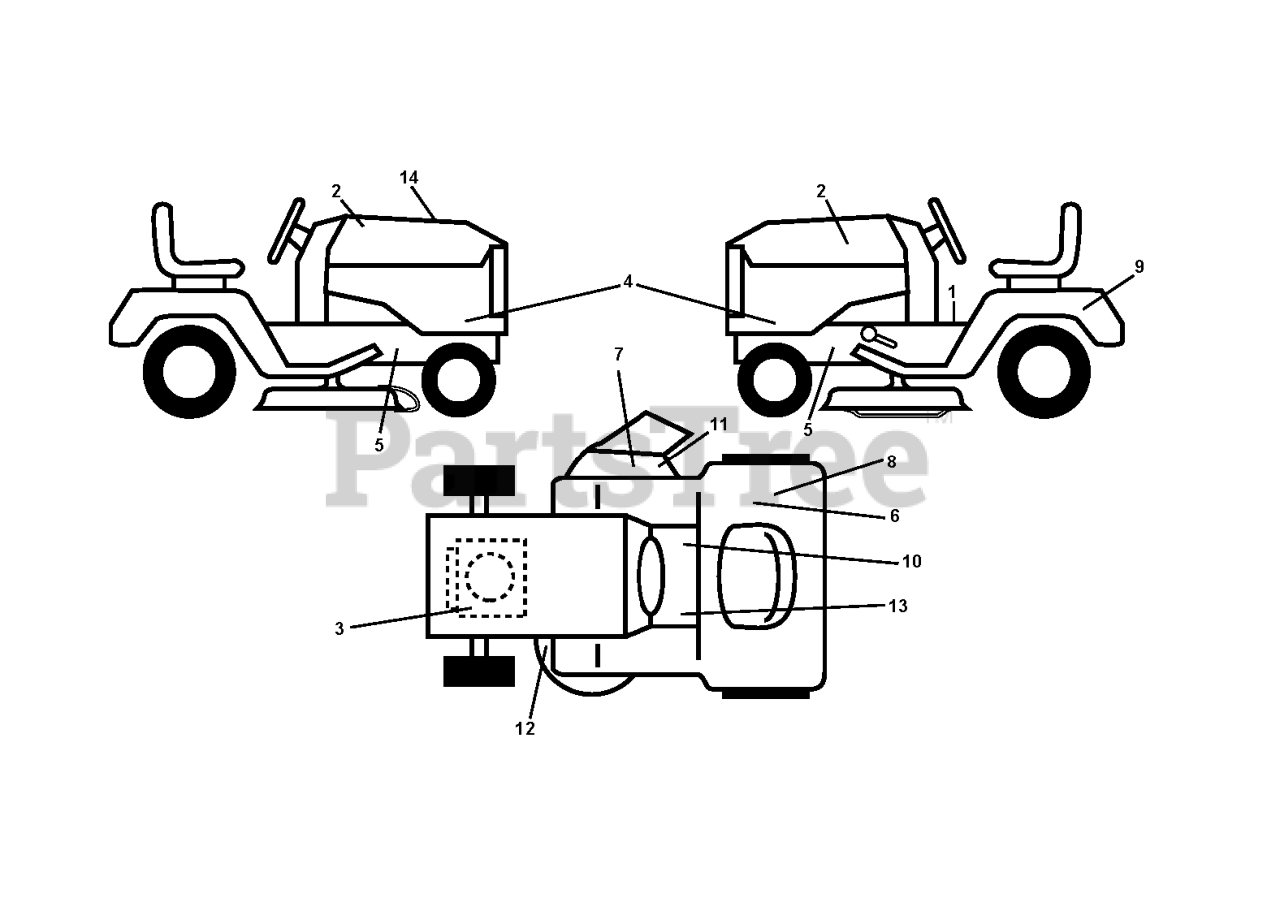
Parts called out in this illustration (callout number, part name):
1	LABEL
2	RP.DECAL.BADGE.170MM.TEXTLOGO
3	DECAL
6	DECAL 80 DBA
7	DECAL.INTERNATIONL.CUTFINGER
8	DECAL
9	DECAL BTRY SYMBOLS
10	DECAL PARK BRAKE
11	DECAL, DEFLECT WARNING
12	DECAL.V-BELT.SCHEMATIC.36/38/9
13	DECAL
